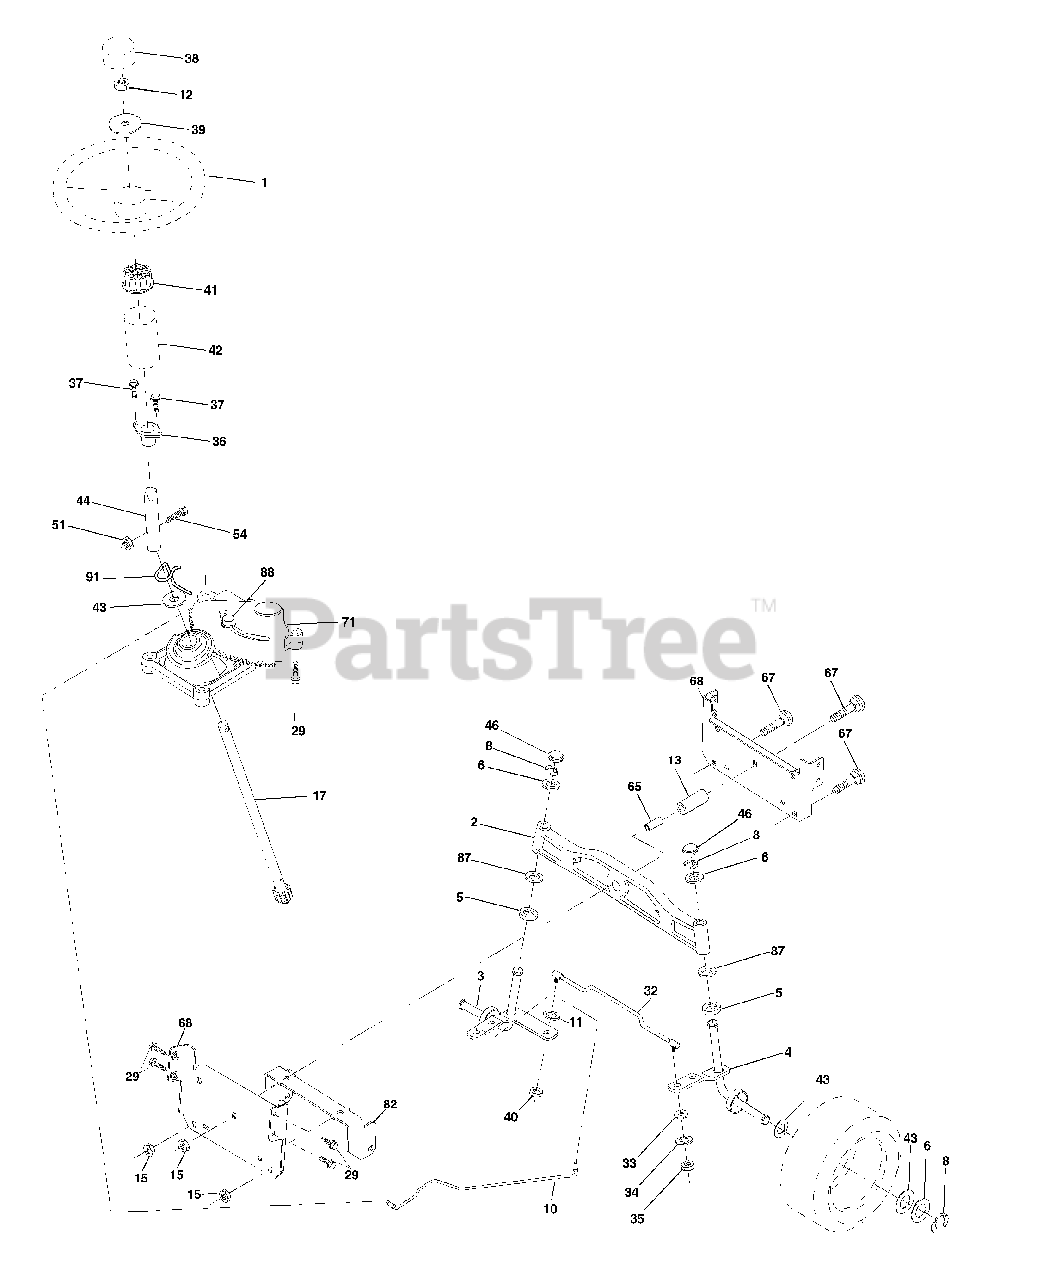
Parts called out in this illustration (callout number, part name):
1	Wheel Steering
2	Axle Asm Cast Iron LT
3	Spindle Asm LH
4	Spindle Asm RH
5	Bearing Race Thrust Harden
6	Washer 25/32 X 1-5/8 X 16 Ga
8	Ring Klip #t5304-75
10	Link Drag
11	Washer Lock Hvy Hlcl Spr 3/8
12	Nut Hex Jam Toplock 1/2-20 UNF
13	Spacer Brg Axle Front
15	Nut Hex Flange Lock
17	Shaft Asm Steering
29	Screw 3/8-16 x .75
32	Rod Tie
33	Washer 11/32 x 3/4 x 16 Ga
34	Washer Lock Hvy Hlcl Spr 5/16
35	Crownlock Nut 5/16-24 Unf
36	Bushing Strg
37	Screw
38	Insert Cap Strg Wh
39	Washer 9/16 ID x 1 1/2 OD 11 Ga.
40	Lock nut
41	Adaptor Wheel Strg
42	Boot Steering Dash
43	Washer 25/32 X 1 1/4 X 16 Ga
44	Extension Steering Shaft
46	Cap Spindle Fr Top Blk
51	Nut Crownlock 1/4-28
54	Bolt Hex 1/4-28 UNF x 1-1/4 Gr. 8
65	Spacer Brace Axle
67	Bolt Rdhd Sq 3/8-16 Unc x 2-3/4
68	Axle, Brace
71	Steering Asm
82	Bracket Susp Chassis Front
87	Washer Flat .781 x 1-1/2 x .14
88	Bolt Shoulder 7/16-20 Unc
91	Clip Steering
